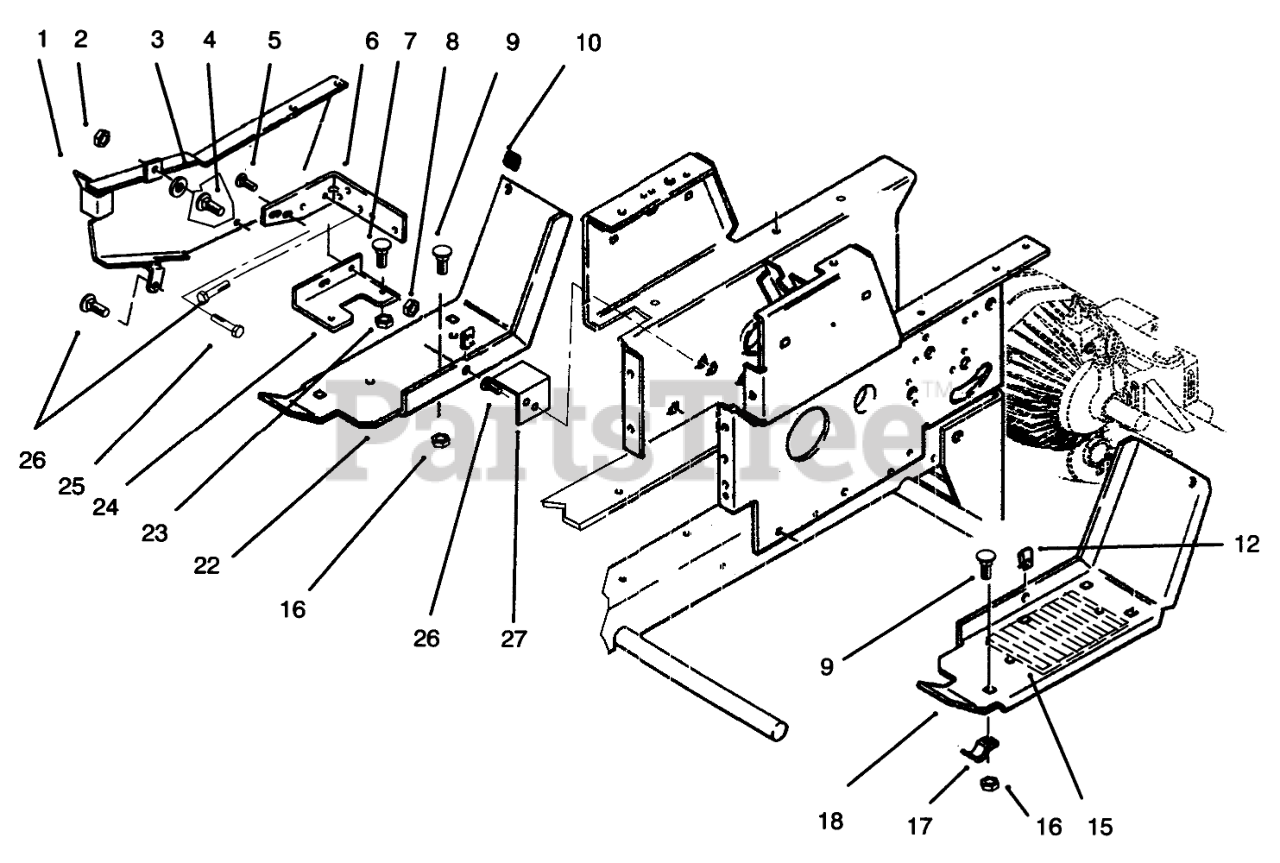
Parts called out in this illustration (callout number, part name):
1	Belt Guard
2	NUT-LOCK, NI
3	NUT-PUSH
4	Screw
5	SCREW-HH
6	BRACKET-BELTB
8	NUT-LOCK, NI
9	BOLT-CARR
10	BUMPER
15	PAD FOOTREST
16	NUT-LOCK, NI
17	BRACKET
18	FOOTREST LH R
22	Footrest-RH
23	Nut
24	FUSE HOLDERB
25	BOLT-CARR
26	Bolt
27	BRCKET-BLT SUTB
